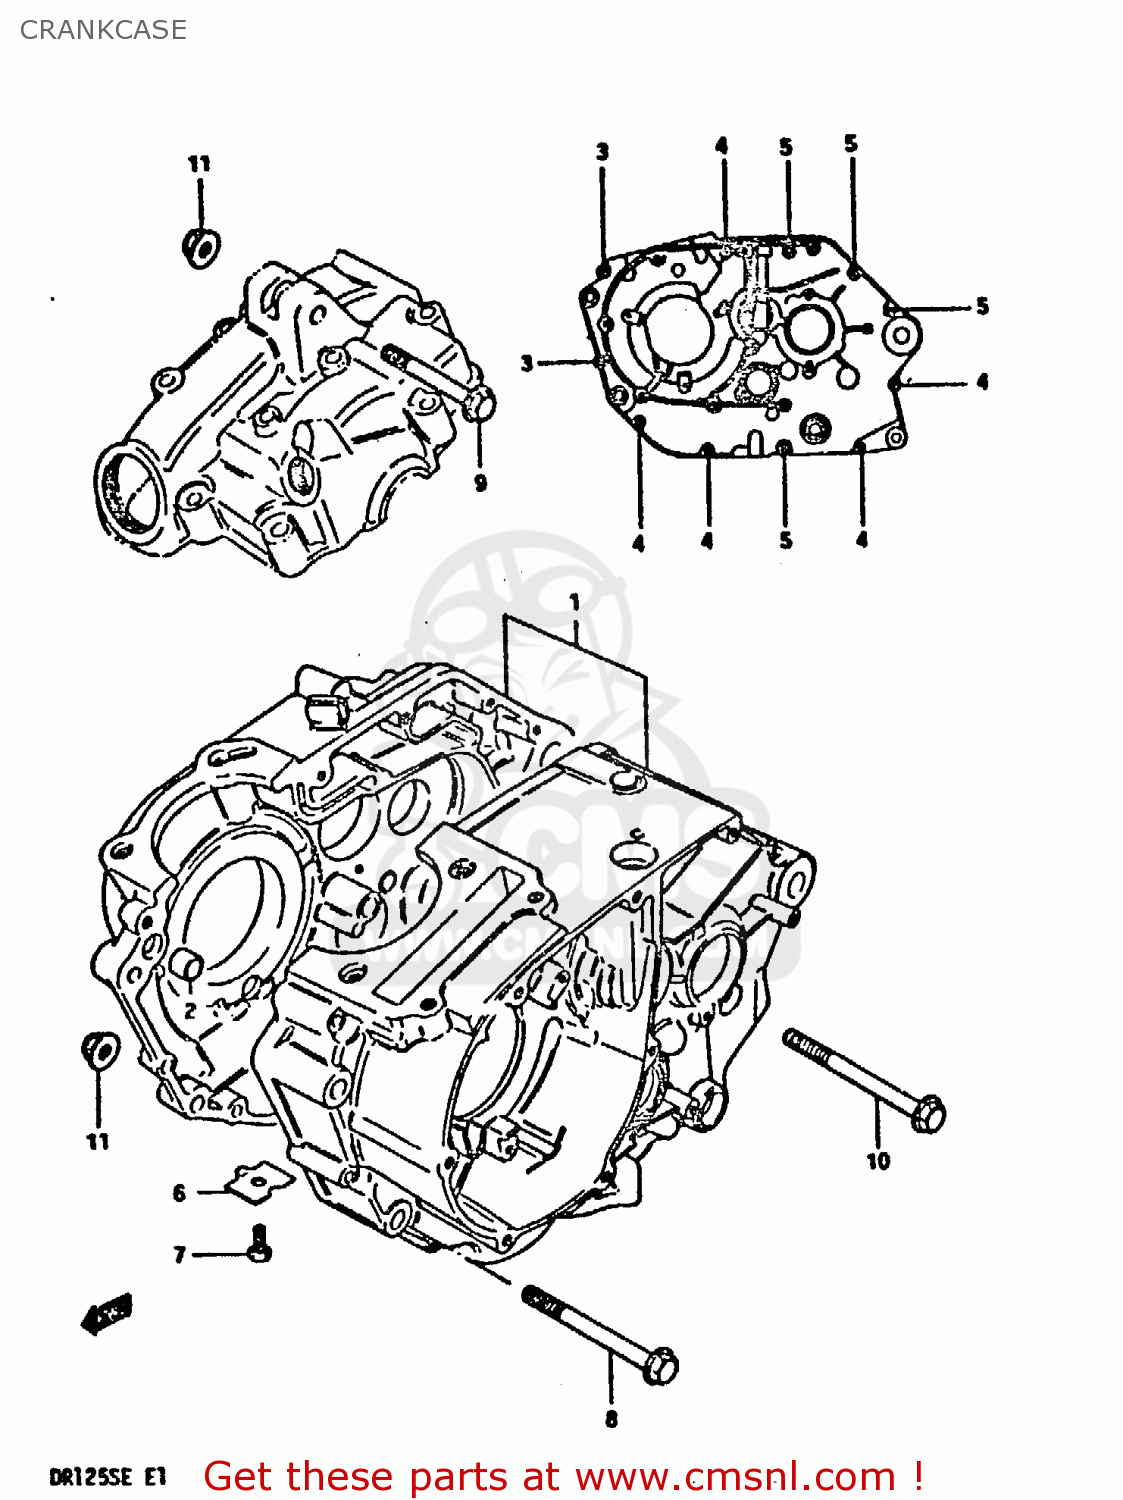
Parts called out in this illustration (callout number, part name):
1	CRANKCASE SET
2	PIN
3	BOLT
4	BOLT (6X60)
5	BOLT (6X75)
6	PLATE,OIL GALLERY PLUG
7	BOLT
8	BOLT(8X80)
9	BOLT 8X50
10	BOLT 8X88
11	NUT
